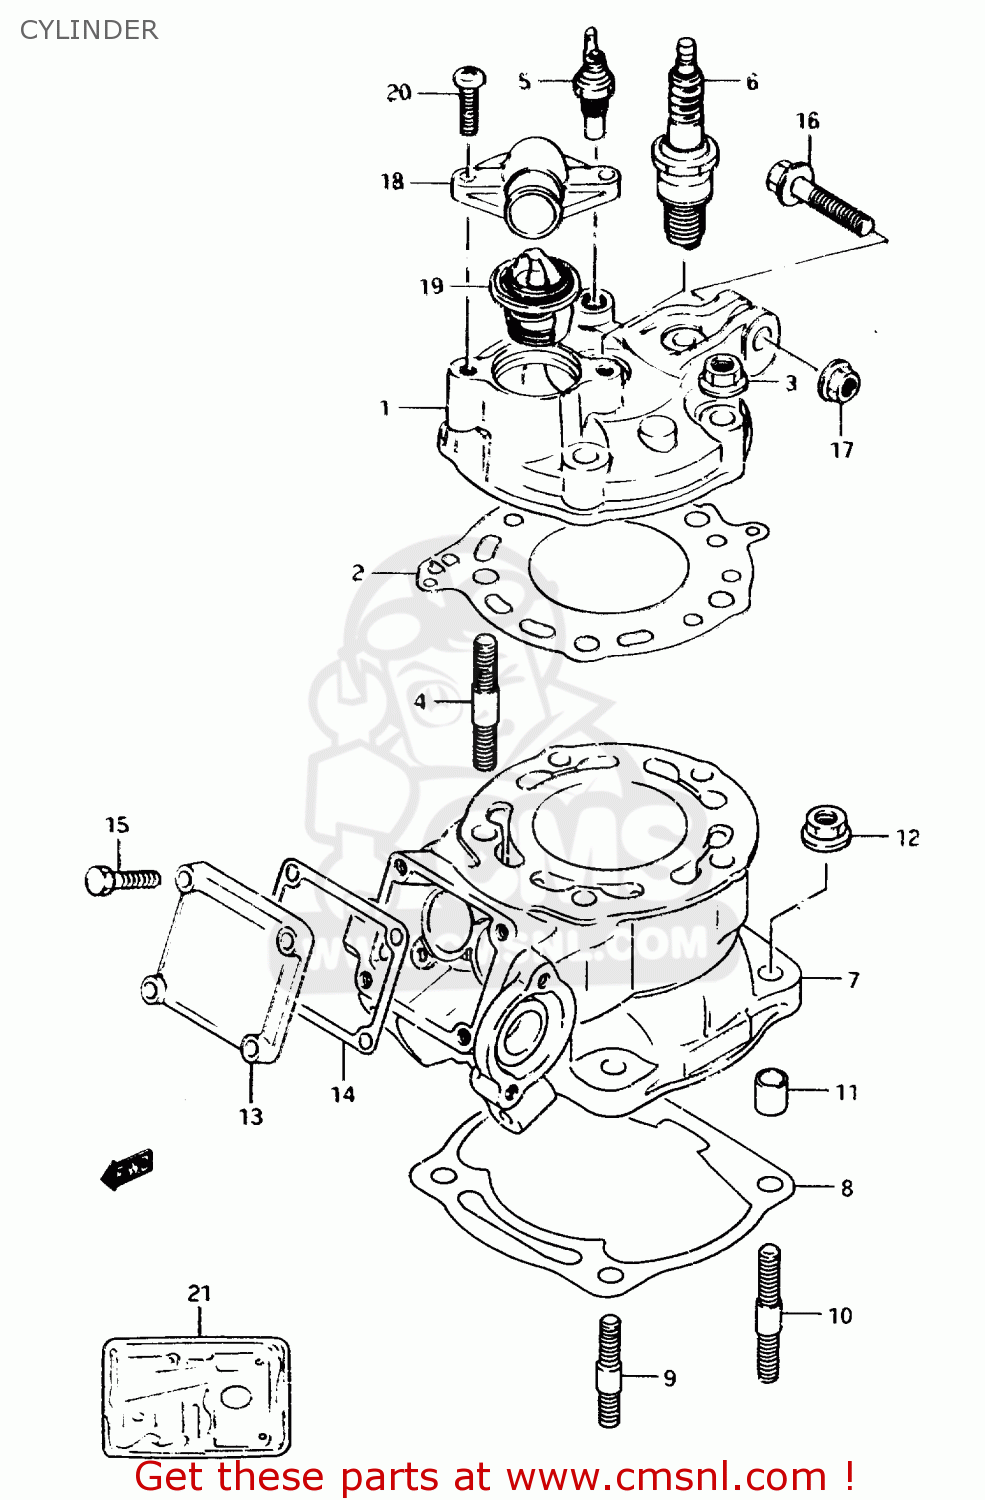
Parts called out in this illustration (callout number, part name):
1	HEAD, CYLINDER
2	GASKET,CYLINDER HEAD (NAS)
3	NUT
4	BOLT,STUD
5	GAUGE,WATER,TM
6	PLUG,SPARK(BR9ES)
7	CYLINDER
8	GASKET,CYLINDER (NAS)
9	BOLT,STUD L:25
10	BOLT,STUD
11	PIN
12	NUT
13	COVER, CYLINDER
14	GASKET,CYL COVER NO.2 (NAS)
15	BOLT
16	BOLT
17	NUT
18	COVER,THERMOSTAT
19	THERMOSTAT COMP,WATER
20	SCREW
21	GASKET SET
